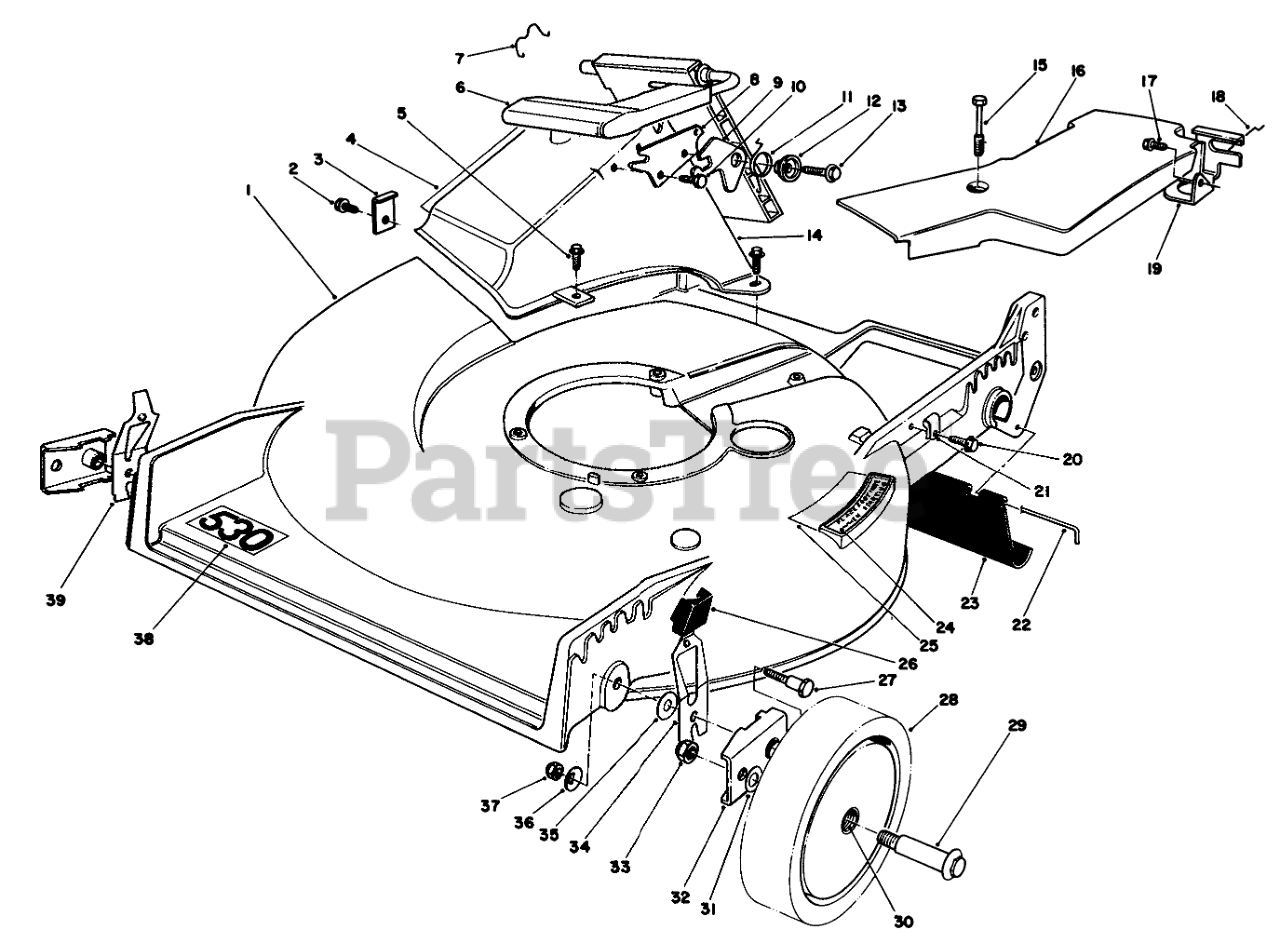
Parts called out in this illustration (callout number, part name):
1	21 SP RB HSG/DECAL
2	SCREW
3	TUNNEL CLIP
4	Decal-Attention
5	SCREW-HWH
6	Discharge Door Assembly
7	DOOR RET SPRING
8	DOOR LATCH PLATE
9	SCREW-PLASTITE
10	SAFETY LATCH
11	TORSION SPRING
12	DOOR SPACER
13	SCREW-HWH
14	Tunnel Discharge
15	SCREW-HHFTF
16	Cover-Belt
17	SCREW-HWHTF
18	RETAINER-CABLE
19	Bracket-Traction Adj.
20	CLAMP-CABLE
21	SCREW
22	ROD-SHIELD
23	SHIELD-TRAILING
24	STEP PAD DECAL
25	Decal-Place Foot Here
26	KNOB-ARM
27	PIVOT SCREW
28	Wheel & Tire Assembly (Incl. Ref. #30)
29	WHEEL BOLT
30	BUSHING
31	WASHER
32	HP PIVOT ARM ASM
33	NUT-LOCK
34	L. HP SPRING ARM ASM
35	WASHER-PIVOT
36	WASHER-BELLEVILLE
37	NUT-LOCK, NI
38	Decal-530
39	R HP SPRING ARM ASM
